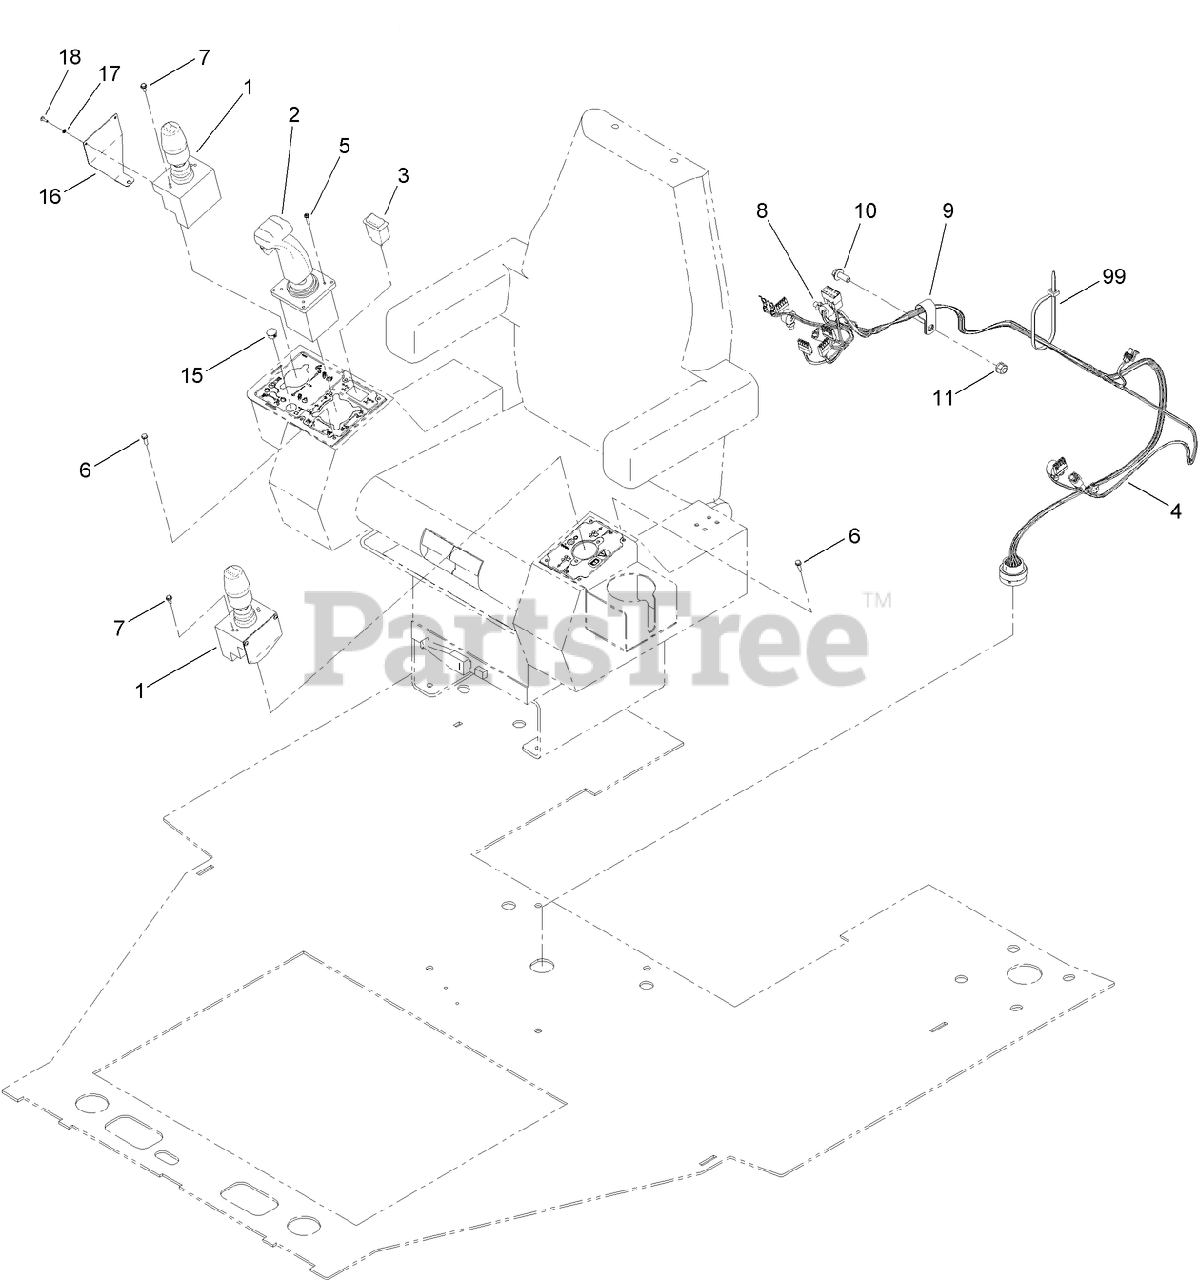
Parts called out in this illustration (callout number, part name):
1	SINGLE AXIS JOYSTICK ASM
2	JOYSTICK-CONTROL (W/ HANDLE)
3	SWITCH-ROCKER, 2 POLE
4	HARNESS-WIRE, SEAT
5	SCREW-SHWH
6	SCREW-HWH
7	SCREW-HWH
8	CLIP-TIE
9	CLAMP-R
10	SCREW-HHF
11	NUT-LOCK, NI
15	PLUG-DOME
16	PLATE-SENSOR, PEDAL
17	WASHER-LOCK / EXT
18	SCREW-PRH
99	TIE-CABLE
